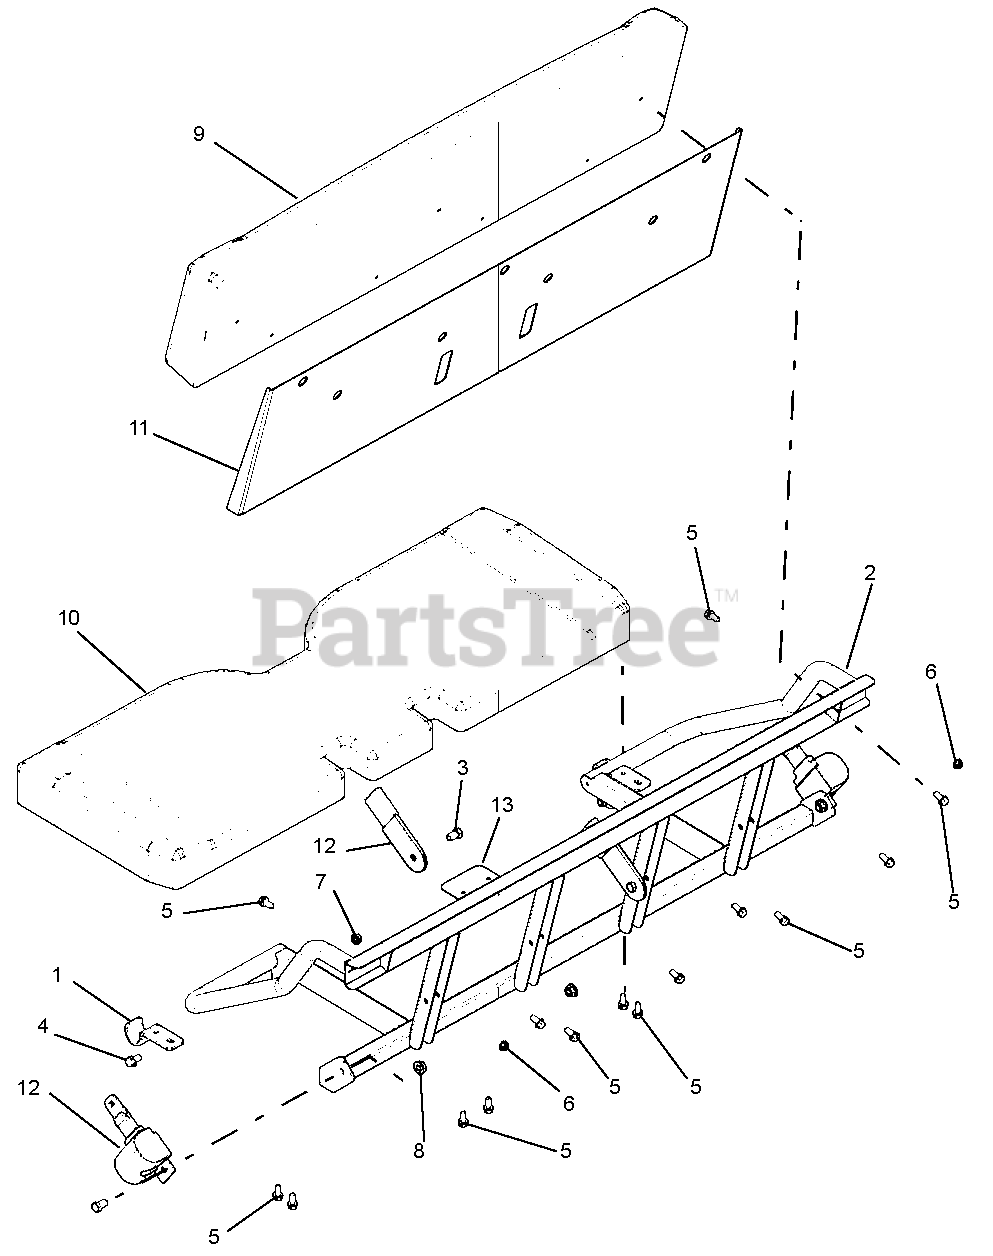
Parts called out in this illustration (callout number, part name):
1	SEAT PIVOT PLATE
2	BENCH SEAT WELDMENT
3	BOLT, HEX .44-14 X 1.00 GR5 YWZC
4	HFSS 3/8-16 X 3/4 LG
5	BOLT, SERRATED HEX FLANGE WASHER HEAD .312-18 x .75
6	NUT, LOCKING TOP FLANGE .312-18 YWZC
7	NUT, HEX TOP FLANGE LOCK .38-16 PLT YWZC
8	NUT, LOCKING TOP .437-14 GRC PL
9	BENCH SEAT BACK
10	BENCH SEAT BOTTOM
11	SEAT BACK PANEL
12	ASSEMBLY, SEATBELT
13	SEAT BOTTOM PLATE
